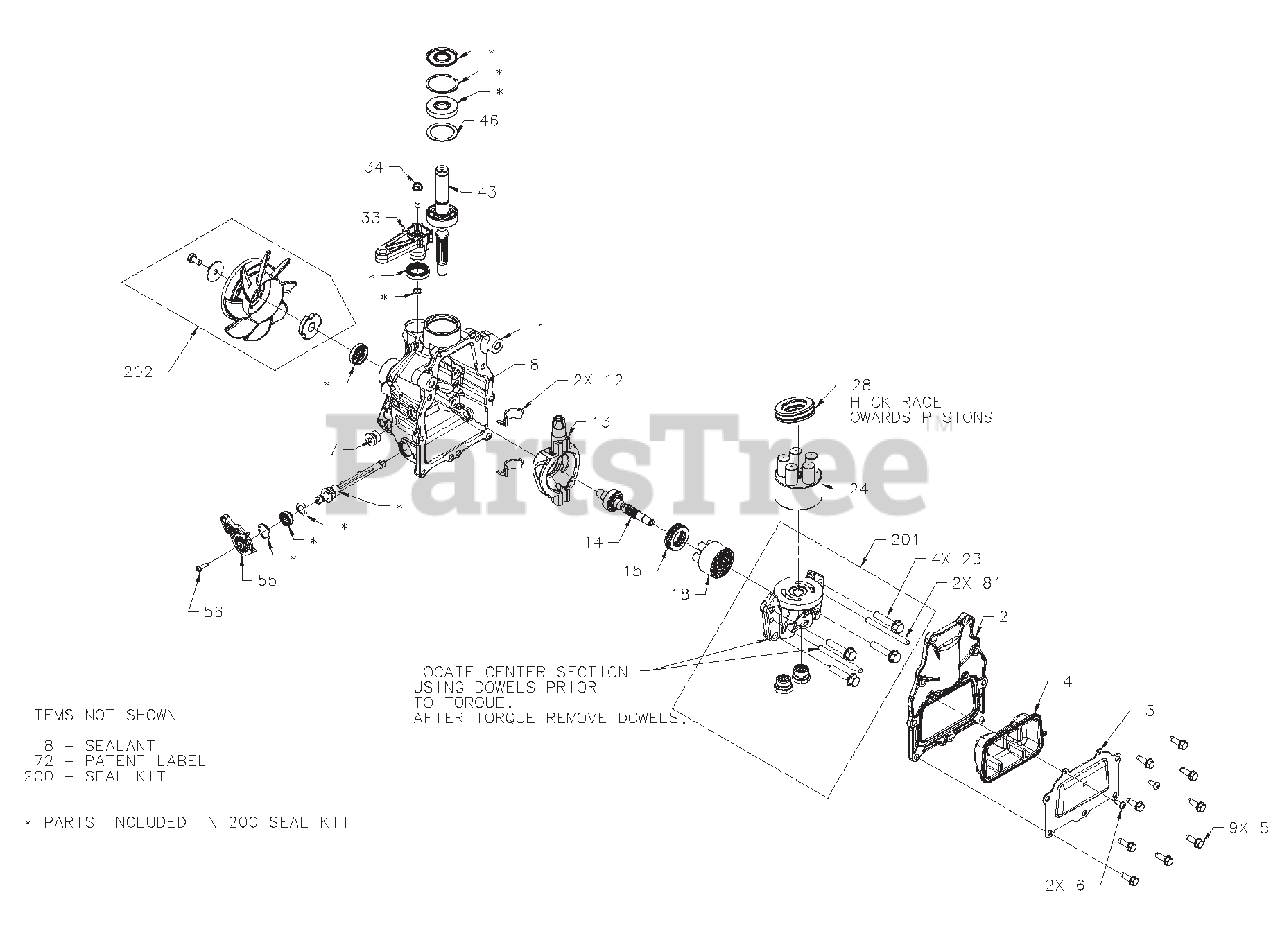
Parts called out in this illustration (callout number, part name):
1	HOUSING, MAIN, SHOT
2	COVER
3	PLATE, EXPANSION
4	BLADDER
5	HFHCS 1/4-20X.75
6	BOLT, SELF TAPPING 1/4-20 X .5
7	PLUG, STEEL (WITH SEAL)
8	SEALANT TUBE 10.1OZ.
12	BEARING, CRADLE
13	SWASH PLATE
14	KIT, INPUT SHAFT
15	BEARING, 21 X 35 X 10
18	KIT, 3CC BLOCK
23	SCREW, HFHCS 5/16-18 X 1.5
24	KIT, 10 CC BLOCK
28	BEARING. THRUST 30 X 52 X 13
33	ARM, CONTROL
34	SCREW,HEX WASHER 1/4-20X1.125
43	KIT, MOTOR SHAFT
46	WASHER 1.23X1.56X.04
55	ARM, BYPASS
56	SCREW, M4X16, WUPLAST
62	HUB, PULLEY DIA 1.41
72	Label, Ptent
81	PIN, STRAIGHT HEADLESS
200	KIT, SEAL
201	KIT, CENTER SECTION
202	KIT, RT-310 FAN REPLACEMENT
